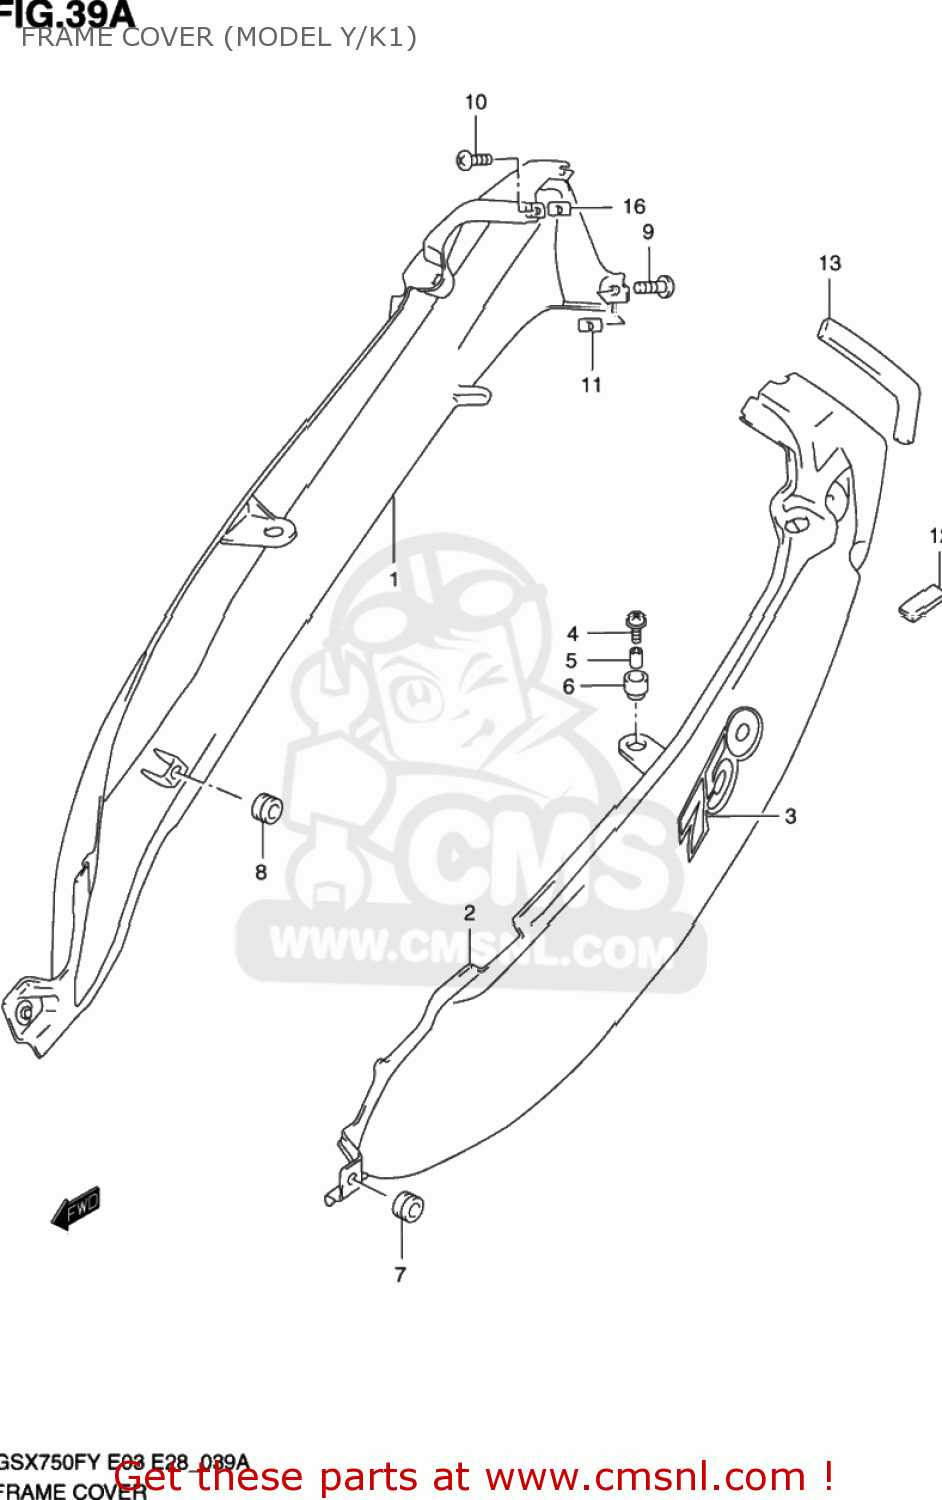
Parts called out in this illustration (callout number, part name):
1	COVER,FRAME,R(GRAY)
2	COVER,FRAME(BL
3	EMBLEM,FRAME COVER
4	SCREW(6X20)
5	SPACER(6.5X10X9.4)
6	CUSHION
7	CUSHION
8	CUSHION
9	SCREW
10	SCREW
11	NUT
12	CUSHION
13	CUSHION,FRAME COVER
